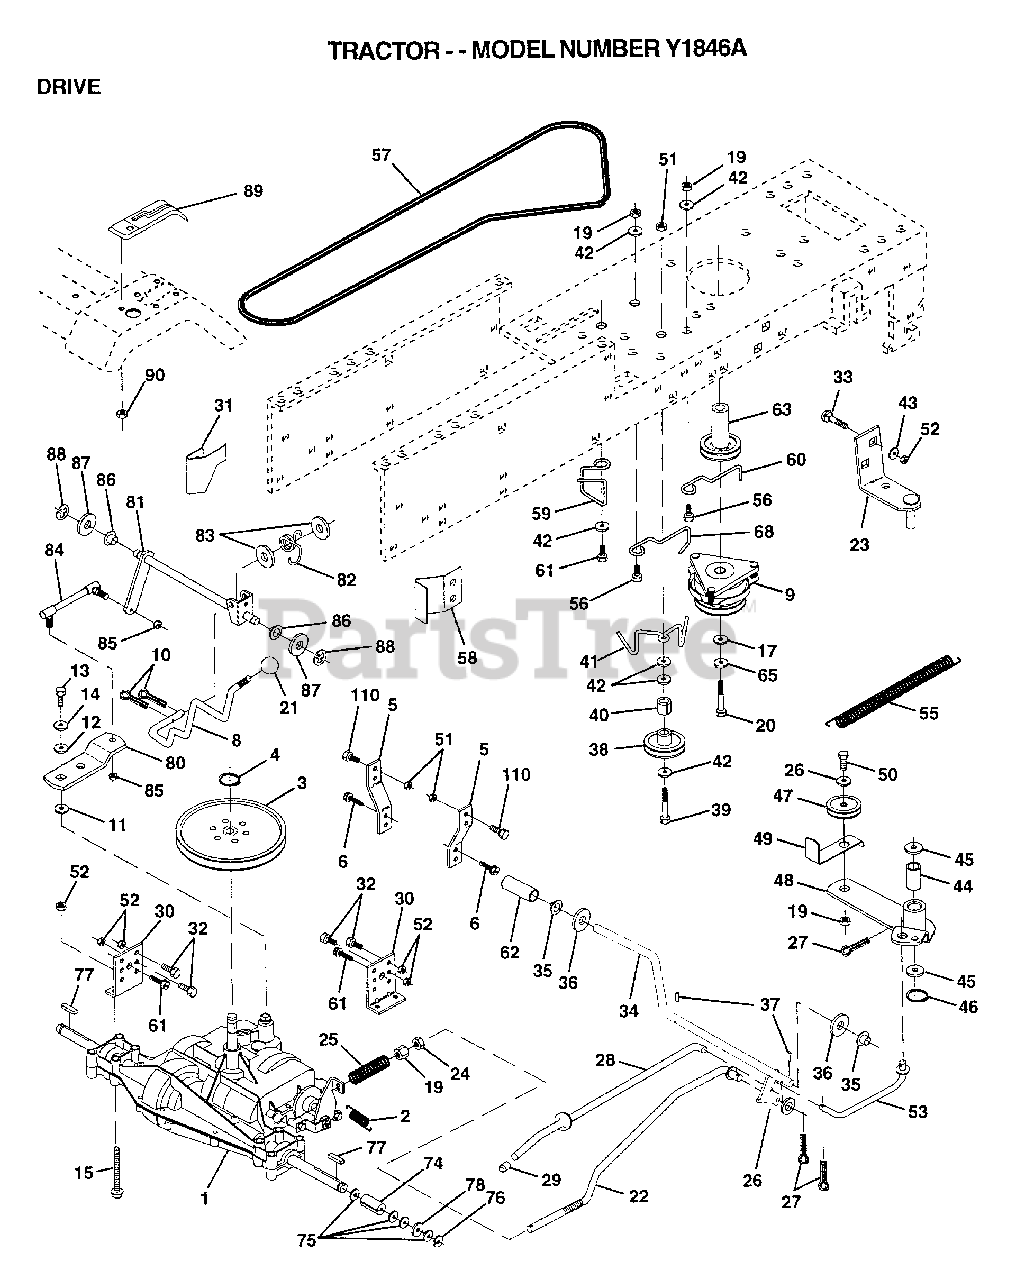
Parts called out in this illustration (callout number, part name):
2	SPRING.BRAKE.RETU
3	PULLEY TRANS
5	STRAP TORQUE
6	SCREW
8	ROD SHIFT FEND LT
10	PIN COTTER 1/8
11	WASH-SHFT PLT LT
12	WASHER
13	BOLT.1/4-28.W/PAT
14	LOCKWASHER
15	BOLT.HX.FLG.5/16
17	WASHER
19	NUT
20	BOLT.7/16-20X4.25
21	KNOB.DUCKHEAD.1/2
22	BRAKE ROD
23	BRACKET.ASM.MTG
24	NUT
25	SPRING ROD LT
26	WASHER
27	COTTER PIN
28	ROD.BRAKE.PARK.LT
29	PLUNGER CAP T
30	TRANSAXLE MTG BKT
31	"KEEPER,BELT LH T"
32	BOLT
33	BOLT
34	SHAFT FOOT PEDAL
35	NYLON BEARING
36	WASHER LT
38	PULLEY.IDLER.FLAT
39	BOLT
40	SPACER T
41	KEEPER BELT
42	WASHER
43	WASHER T
44	"LY, BEARING"
45	WASHER LT
46	KLIP RING
48	ARM IDLER
49	RETAIN BELT
53	"LINK, CLUTCH T"
55	"SPRING, RETURN LT"
58	"KEEPER,BELT RH T"
59	KEEPER BELT CNTSP
60	KEEPER BELT ENGLH
61	SCREW
62	PEDAL COVER T
63	PULLEY CLU ELEC
65	LOCKWASHER
68	"KEEPER,BLT ENG LT"
74	SPACER LT
75	WASHER
76	E-RING LT
77	SQUARE KEY
78	WASHER
80	ARM SHIFT TRANS
81	SHAFT ASM.SHIFT
82	"SPRING,TORSION"
83	WASHER
84	TIE ROD
85	NUT.CNT.LOCK.1/4
86	BUSHING
87	WASHER D
88	KLIP RING
90	NUT
